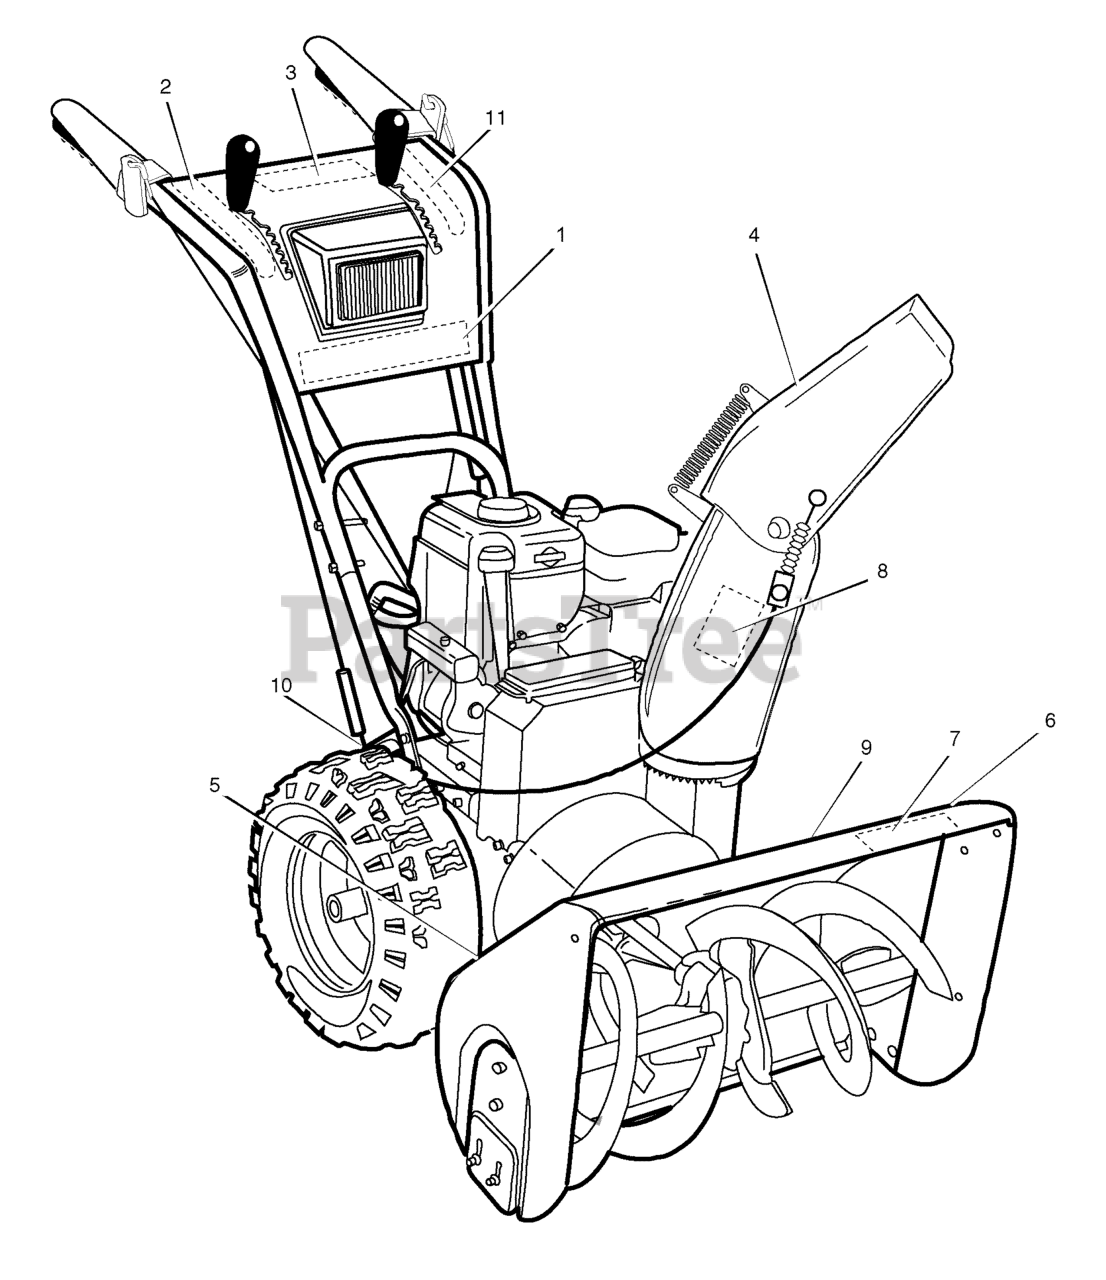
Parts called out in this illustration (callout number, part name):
1	DECAL, ULTRA, PANEL
2	DECAL, SPEED PANEL
3	DECAL, TRACTION, AUGER SYMBOLS
4	DECAL, ISO CHUTE
5	DECAL, ISO AUGER
6	DECAL, FACE HEAD PHONES
7	DECAL, ULTRA 1450/74 TOP AUGER
8	DECAL, POWER 2 STEER
9	DECAL, 104db CE
10	DECAL, ID PLATE
11	DECAL, REMOTE CHUTE P4 XPT
